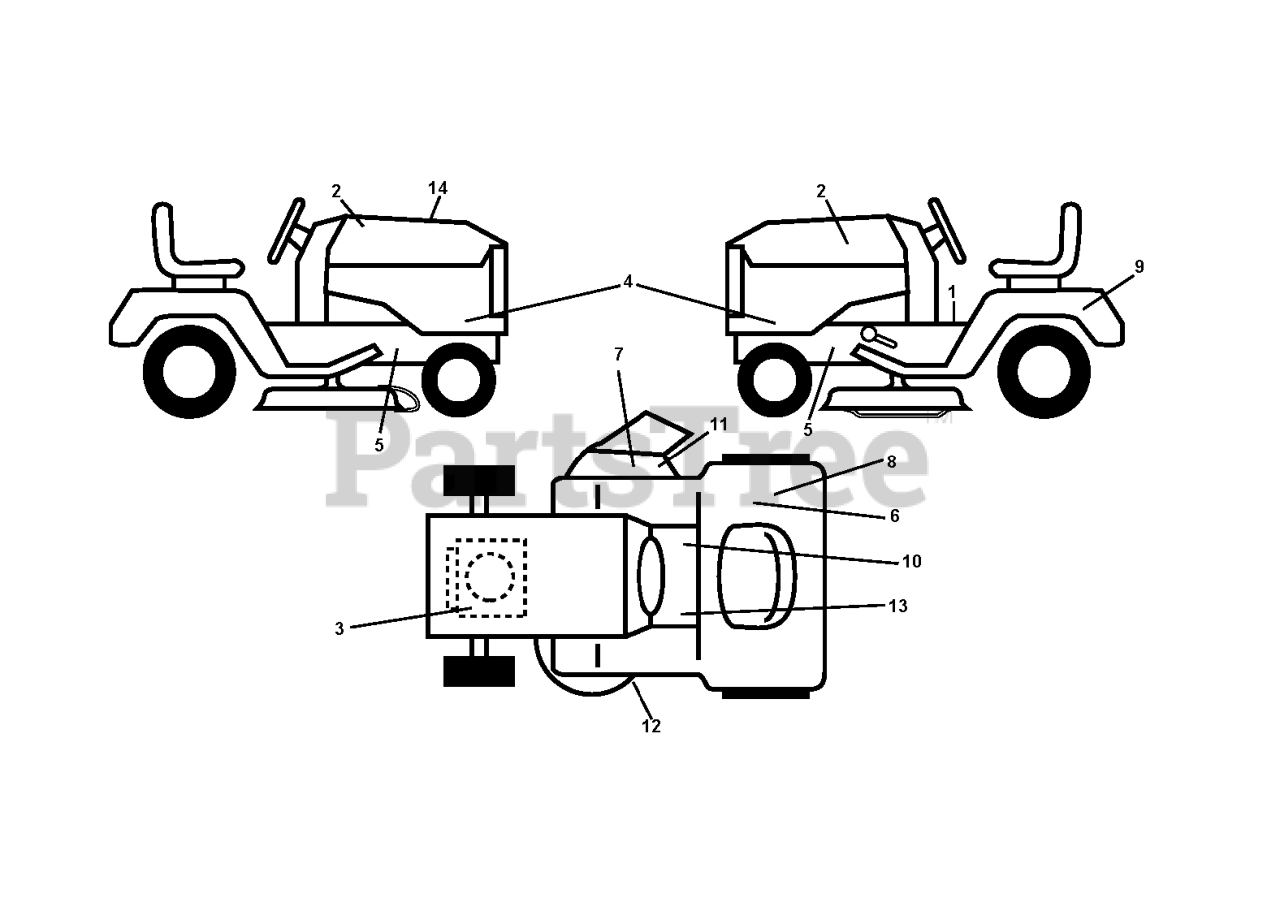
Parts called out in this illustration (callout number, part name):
1	LABEL
2	DECAL.BADGE.170MM.TEXTLOGO.
3	DECAL
6	DECAL 80 DBA
7	DECAL.INTERNATIONL.CUTFINGER
8	DECAL
9	DECAL BTRY SYMBOLS
10	DECAL PARK BRAKE
11	DECAL, DEFLECT WARNING
12	DECAL.V-BELT.SCHEMATIC.36/38/9
13	DECAL
